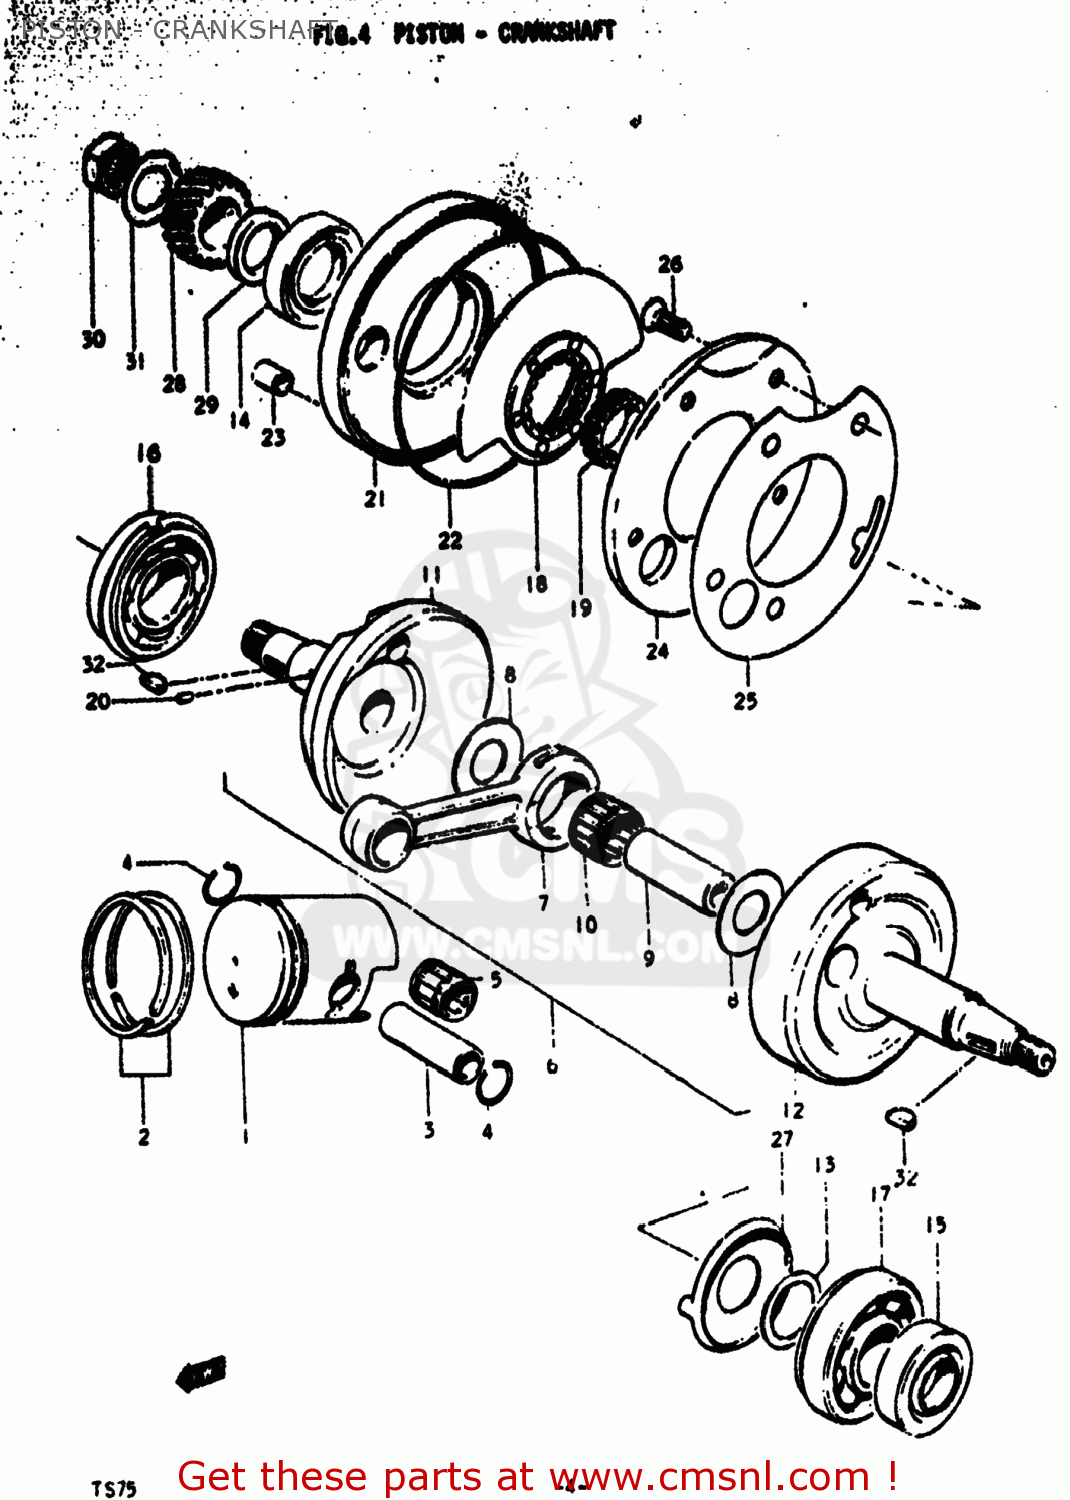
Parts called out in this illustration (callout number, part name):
1	PISTON
2	RING SET,PISTON
3	PIN,PISTON
4	RING,SNAP
5	BEARING
6	CRANKSHAFT ASSY
7	CONNECTING ROD
8	WASHER(19X32X1)
9	PIN,CRANK
10	BEARING
11	CRANKSHAFT,RIGHT
12	CRANKSHAFT,LEFT
13	THRUST WASHER
14	OIL SEAL (25X44X7)
15	OIL SEAL
16	BEARING(20X52X15)
17	BEARING(20X47X14)
18	VALVE,ROTARY
19	GUIDE,ROTERY VALVE
20	PIN 3X5
21	SEAT,CRANKCASE OUTER VALVE
22	O RING(D:2.4,ID:100.6)
23	PIN
24	SEAT,INNER VALVE
25	GASKET,ROTERY VALVE INNER SEAT (NAS)
26	SCREW
27	PLATE,CSHAFT OIL GUIDE
28	GEAR,PRIMARY DRIVE
29	SPACER(20X25X10)
30	NUT
31	WASHER
32	KEY
